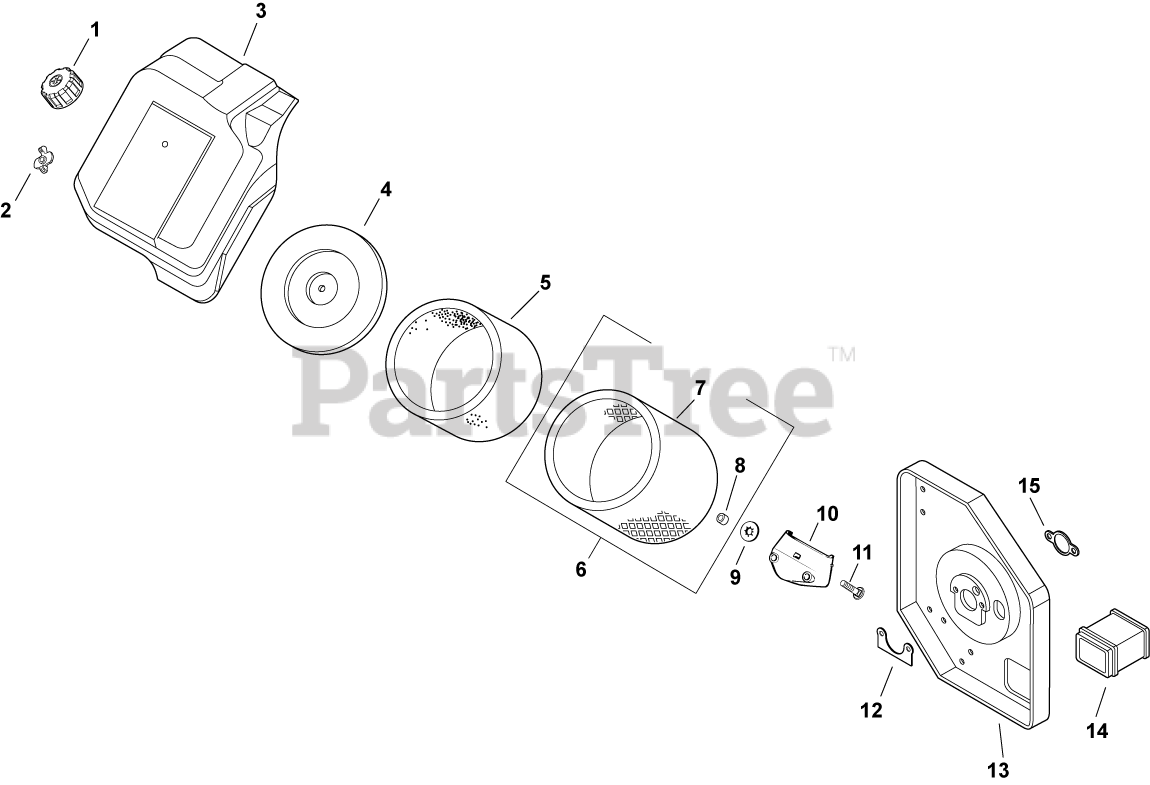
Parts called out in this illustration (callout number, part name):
1	KNOB, COVER
2	NUT, WING
3	COVER, AIR CLEANER BASE
4	COVER, AIR CLEANER
5	PRE-CLEANER
6	KIT, AIR CLEANER ELEMENT
7	ELEMENT, AIR CLEANER (KM) - Also available Retail Packaged 47 883 01-S1 Air Filter Kit
8	SEAL, INNER AIR CLEANER
9	RETAINER, RING
10	CUP, FUEL SPITBACK
12	GASKET, AIR CLEANER BASE
13	BASE, AIR CLEANER
15	GASKET, AIR CLEANER BASE
